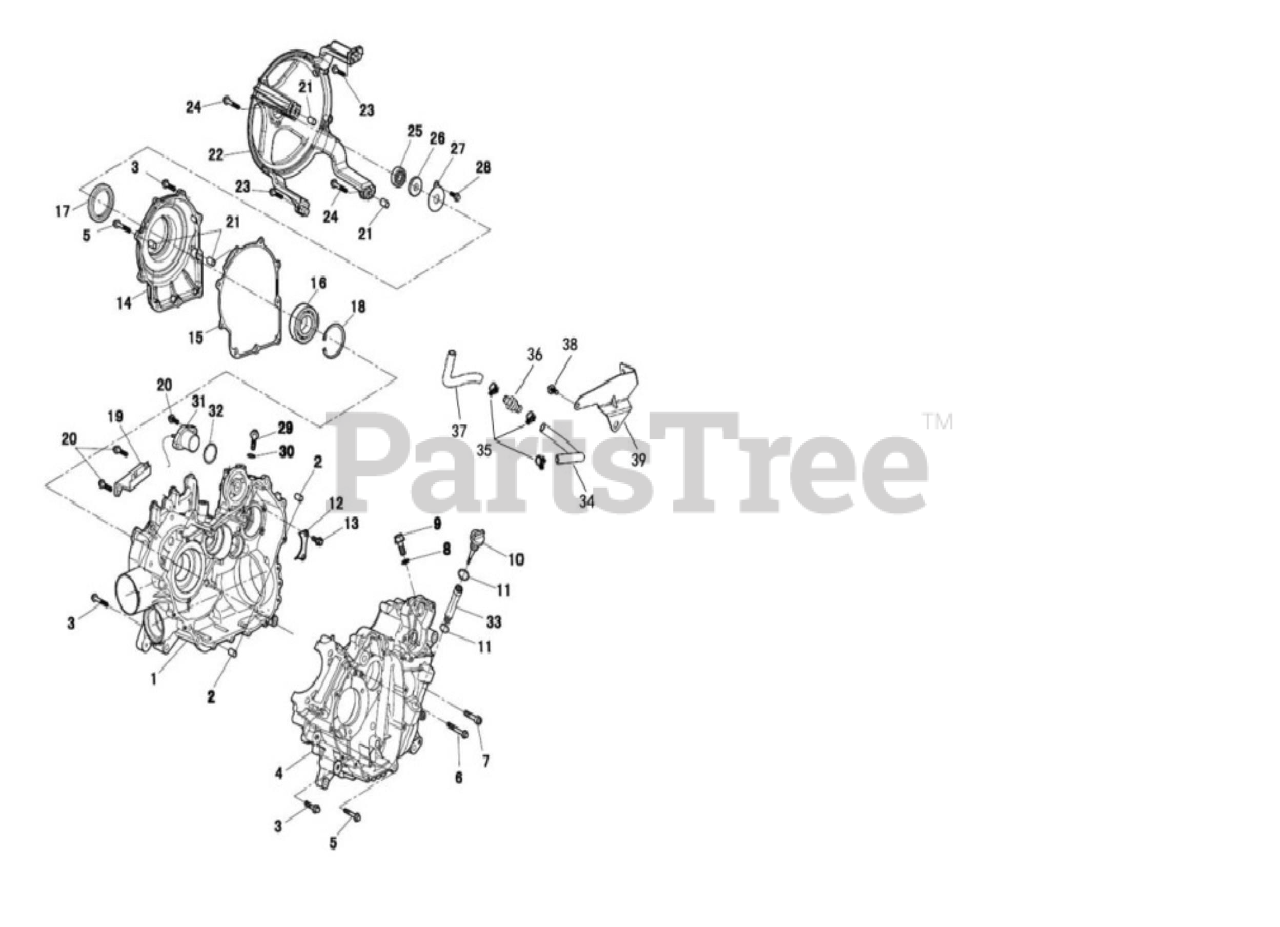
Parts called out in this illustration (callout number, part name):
1	RIGHT CRANKCASE ASSEMBLY
2	Pin,Dowel 9X12X16
3	Hex flange bolts M6X30
4	LEFT CRANKCASE ASSEMBLY
5	Hex flange bolts M6X40
6	Hex flange bolts M6X85
7	Hex head cap screw M8X40
8	Aluminum Washer 14X20X1.5
9	Hex flange Screw Plug M14X1.5X16
10	Plug,Oil Level
11	O-Ring 18X3.5
12	Press Plate,Main Shaft Bearing
13	Hex flange bolts M6X16
14	Bearing Block,outer cover
15	Gasket,Bearing Block
16	Bearing 16010
17	Oil Seal 35X65X9
18	Circlip for hole ?80
19	STRAP CVT VENT-PIPE PLATED
20	Hex head bolt & plain washer M6X16
21	Pin,Dowel 10X16
22	Shield Bracket,Clutch
23	Hex flange bolts M6X32
24	Hex flange bolts M6X40
25	BEARING 62012Z
26	Oil Seal 12X32X6
27	Press Plate,Bracket oil seal
28	Hex flange bolts M6X16
29	Hex flange bolts M10X1.25X16
30	Aluminum Washer 10X16X1.2
31	Sensor,Gear Indicator
32	O-Ring 29.6X2.4
33	Guiding Tube,Oil Level
34	EXHAUST GAS RECOVERY TUBE?
35	SPRING CLAMP
36	NON PRESSURE CHECK VALVE
37	EXHAUST GAS RECOVERY TUBE
38	Hex flange bolts M6X30
39	AIR CLEANER STRAP - PLATED
